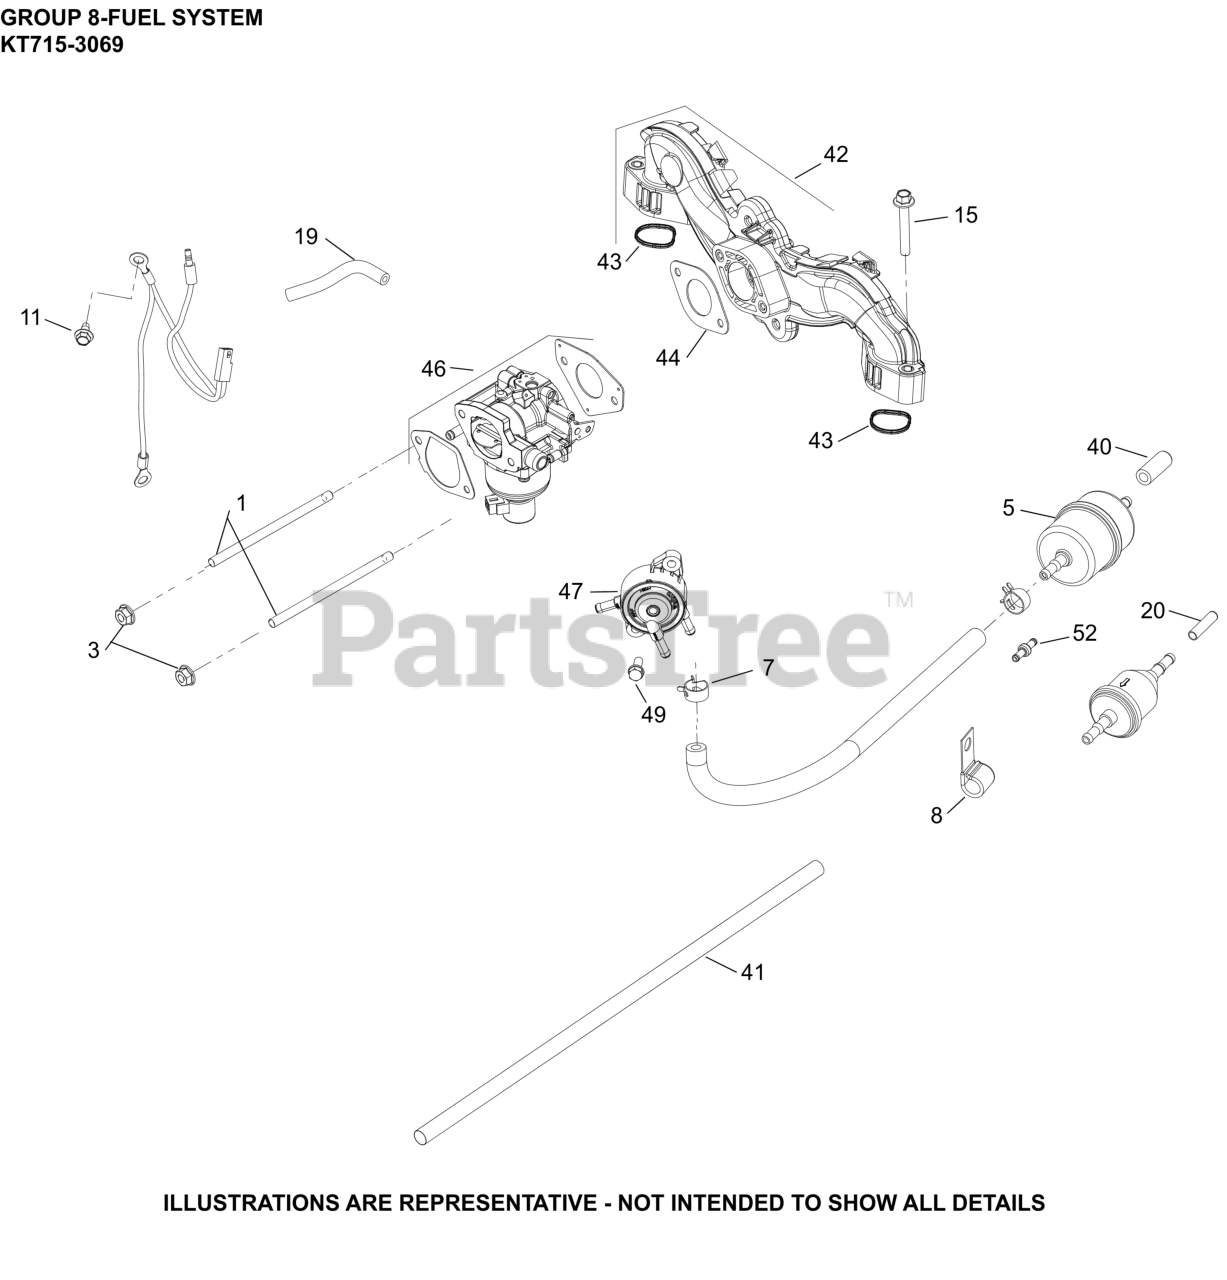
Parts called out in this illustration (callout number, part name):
3	NUT, FLG M6X1.0
5	FILTER, FUEL
7	SPRING CLAMP, HOSE
8	CLIP, CABLE (KM)
11	SCREW, THREAD FORMING
15	SCREW, FLG M6X1.0X40
19	HOSE, EVAPORATIVE 20"- (#24326143S)
20	CAP, MASKING
40	MASKING CAP
41	SLEEVE, ANTI-ABRASION
42	INTAKE MANIFOLD W/GASKETS
43	O-RING, INTAKE PORT
44	GASKET, CARBURETOR (PIM, CV)
46	KIT,CARB (NIKKI)
47	PUMP, FUEL (PULSE)
49	SCREW, HEX HEAD
52	FITTING, FUEL SYSTEM
NI	KIT, HIGH ALT (4000-8000 FT)(NIKKI)
NI	KIT, OVERHAUL NIKKI G-TYPE TWIN
NI	KIT, BOWL WITH O-RINGS NIKKI G-TYPE TWIN
NI	KIT, FLOAT AND NEEDLE NIKKI G-TYPE TWIN
NI	KIT,CHOKEREPAIR NIKKI G-TYPE T-DISC.
NI	KIT,THROTTLE SHAFT(19MM)NIKKI-DISC.
NI	KIT, O-RING (NIKKI)
NI	KIT, SOLENOID (NIKKI)
